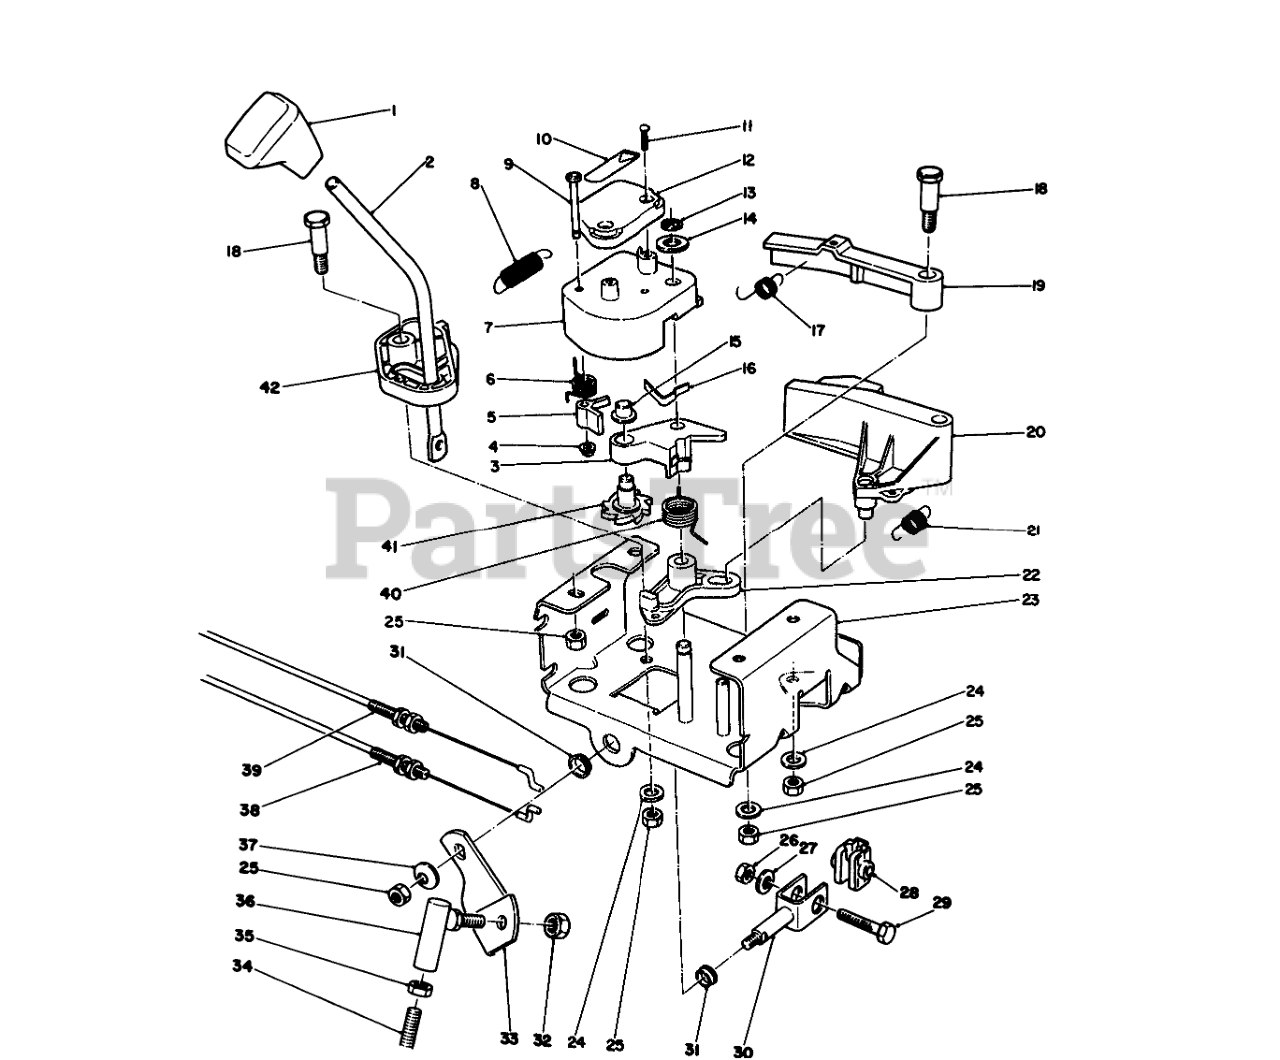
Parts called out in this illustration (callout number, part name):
1	KNOB-SHIFT
2	ROD-SHIFT
3	LEVER-WHEEL, INDEX
4	NUT-PUSH
5	TANG-INDEX
6	SPRING-TORSION
7	LATCH-LEVER
8	SPRING-EXTENSION
9	PIN-TANG
10	DECAL
11	SCREW-PPH
12	COVER-LATCH
13	RING-RETAINING
14	WASHER-THRUST
15	RETAINER-PUSH ON
16	SPRING-FLAT
17	SPRING-EXTENSION
18	SCREW-SHOULDER
19	LEVER-LOCKOUT
20	LEVER-REVERSE
21	SPRING-EXTENSION
22	LEVER-REVERSE, SWITCH
23	Frame-Control
24	WASHER-PLAIN
25	NUT-LOCK, NI
26	NUT-LOCK, NI
27	WASHER-FLAT
28	RETAINER-ROD, SHIFT
29	CAPSCREW
30	CLEVIS ASM
31	BUSHING
32	NUT-LOCK, NI
33	BRACKET-SHIFT
34	ROD-BENT SHIFT, LOWER
35	NUT-HJ
36	JOINT-BALL
37	WASHER-BELLEVILLE
38	CABLE-GEARBOX
39	CABLE-ARM, LATCH
40	SPRING-TORSION
41	WHEEL-INDEX
42	BASE-LOCKOUT
